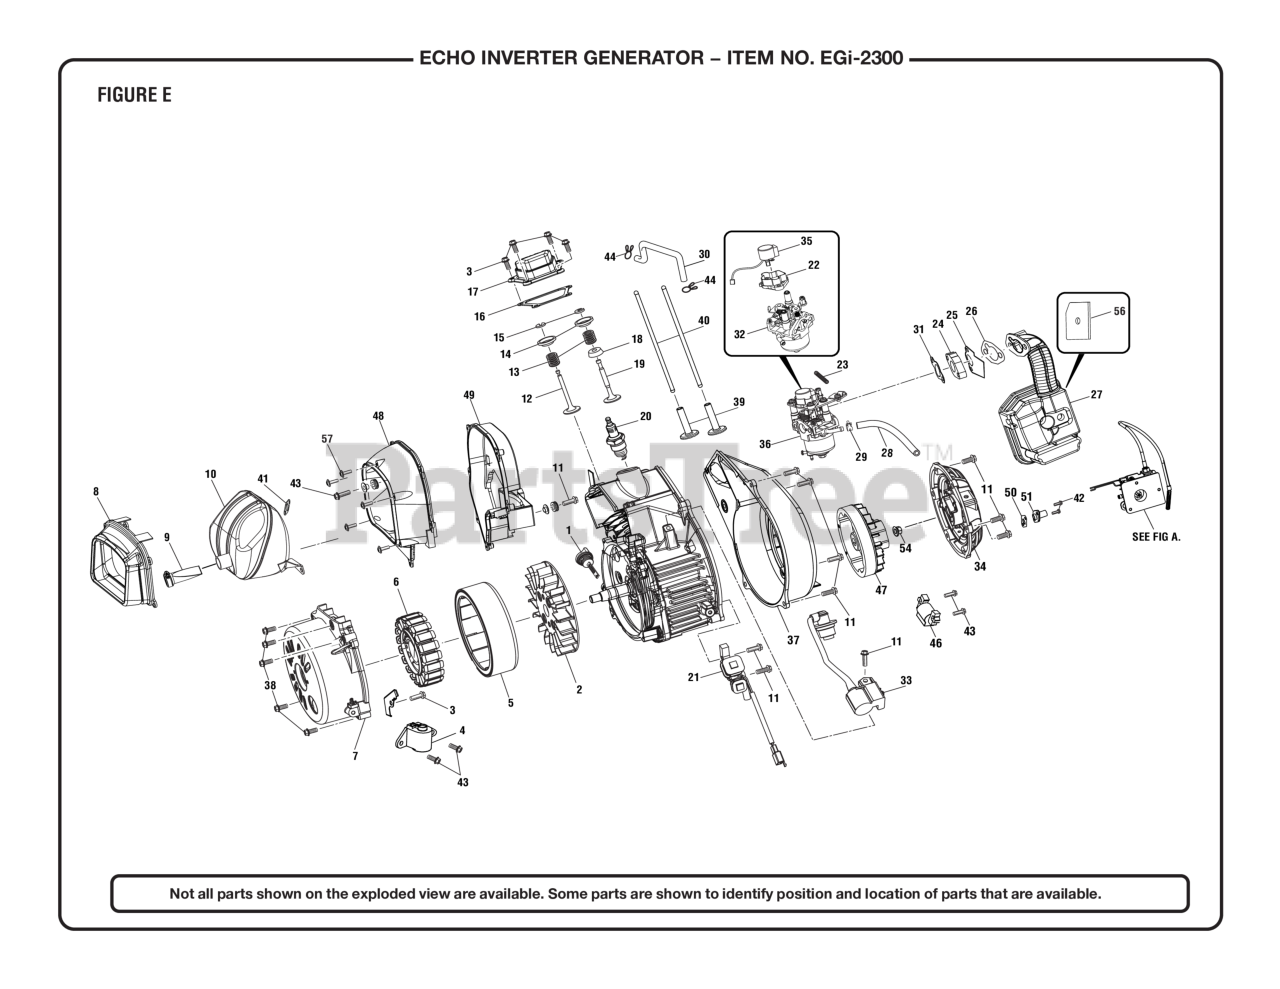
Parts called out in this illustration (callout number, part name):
1	DIPSTICK, OIL
2	FAN, ALTERNATOR COOLING
4	SENSOR, LOW OIL
7	COVER, ALTERNATOR
8	Muffler Heat Shield
9	Spark Arrestor
12	VALVE, EXHAUST
13	SPRING, VALVE
14	PLATE, VALVE SPRING SEAT
15	CLAMP, VALVE LOCK
16	GASKET, VALVE COVER
17	COVER, VALVE
18	SEAT, INTAKE VALVE SPRING
19	VALVE, INTAKE
20	PLUG, SPARK
21	SENSOR, RPM
22	HOUSING, GOVERNOR MOTOR
23	SPRING, COMPRESSION
24	THERMAL INSULATOR, CARB
26	GASKET, AIR-BOX
27	ASSY., AIR FILTER
28	HOSE, FUEL
29	CLAMP, FUEL LINE
30	BREATHER
31	GASKET, CONNECTION BLOCK
32	CARBURETOR
33	COIL, IGNITION
34	ASSY., RECOIL STARTER
35	MOTOR, GOVERNOR
36	ASSY., CARBURETOR
37	COVER, ENGINE
39	LIFTER, VALVE
40	ROD, PUSH
41	GASKET, MUFFLER
45	BREATHER, ENGINE HOSE
46	ASSY., ENGINE
47	FLYWHEEL
48	Muffler Cover (1)
49	Muffler Cover (2)
50	OIL RING
52	ASSY., FILL VALVE
53	SEAL, OIL
54	NUT, FLYWHEEL
55	BOLT, CYLINDER HEAD
56	FILTER, AIR
58	GASKET, CYLINDER HEAD
59	HEAD, CYLINDER
60	ASSY., INTAKE ROCKER ARM
61	ASSY., EXHAUST ROCKER ARM
62	SHAFT, ROCKER ARM
63	STUD, INTAKE
64	STUD, EXHAUST
